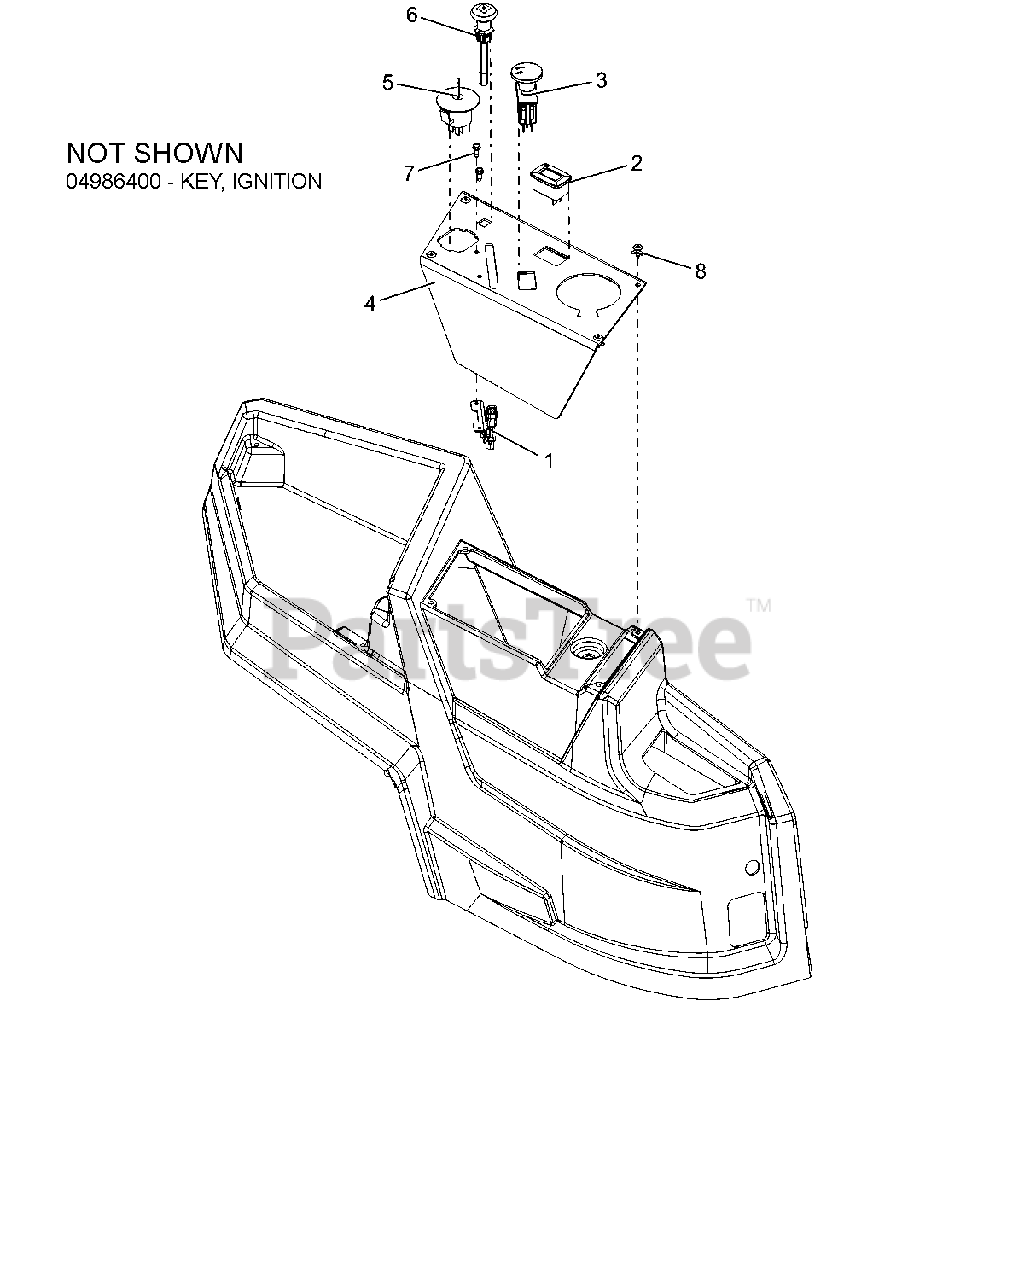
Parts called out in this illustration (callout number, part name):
1	CABLE - THROTTLE CONTROL
2	METER, HOUR W/MAINTENANCE
3	SWITCH, CLUTCH (YELLOW)
4	PANEL, CONTROL
5	KEYSWITCH-IGNITION 4 POS
5	KEYSWITCH-IGNITION 3 POS
6	CABLE - CHOKE, SNAP-IN
7	@SCR-TAP 10-24X.50 HWH TR YWZC
8	RIVET, PLASTIC .195 DIA.
